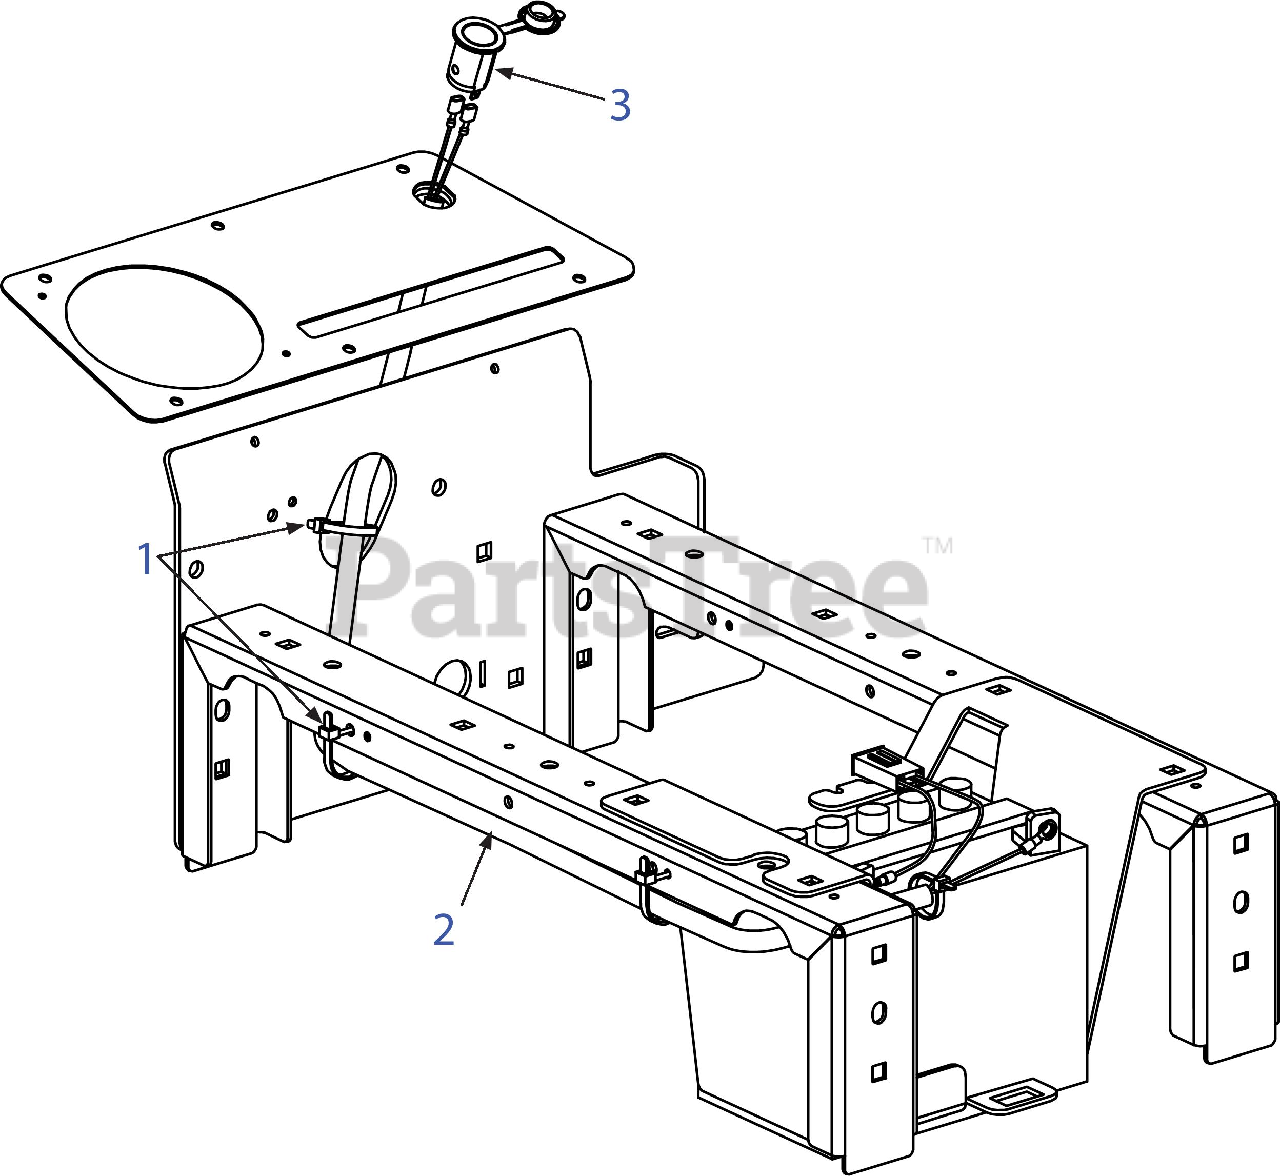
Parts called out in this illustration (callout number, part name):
1	Cable Tie
2	Wire Harness Assembly (5 amp fuse)
3	12V Power Recepticle
